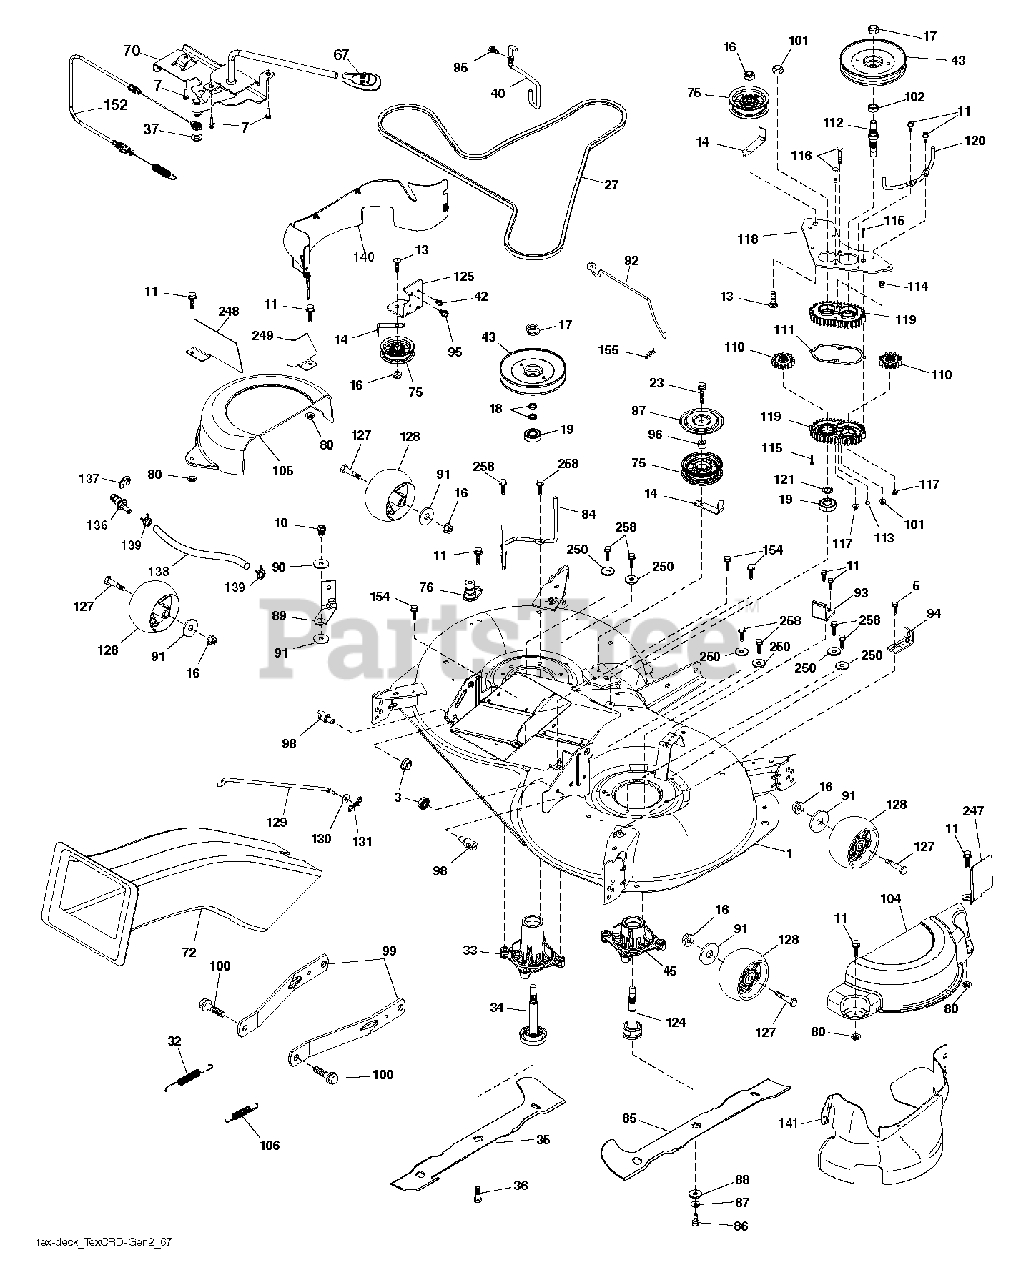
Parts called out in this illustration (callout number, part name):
1	DECK SVCX.107HP.C.BL.498
3	NUT LOCK HEX FLANGE 5/16-18
5	BOLT.5/16HEX.WHS.HD
7	SCREW.#10 X 0.750.BOS
10	SCREW 3/8-16X1
11	SCREW.1/4-20X5/8
13	BOLT.3/8-16X1.50
14	KEEPER, BELT IDLER
16	NUT LOCK FLG 3/8-16 UNC
17	NUT.FLANGE.LOCK.TOP
18	WASHER.SPACER.MANDREL
23	SCREW LT
27	BELT BELT. MOWER DRIVE 97.4 EL
32	SPRING RETURN
33	HOUSING.MANDREL.REV.TALL.N/GRS
34	SHAFT ASM.REV.TALL.N/GREASEBL
35	BLADE.107.LH.SINGLE.NON.QD
36	BOLT.WASHER.ASM.7/16-2
37	WASHER
40	KEEPER BELT ENGINE LH
42	SCREW
43	PULLEY PULLEY MANDREL 5.438 PD
45	RP HOUSING.MANDREL.REV.REVS.
67	HANDLE.CLUTCH.CABLE.LT
70	CLUTCH.ASM.MANUAL.YT.PREDATORQ
72	RB CHUTE 107/97 TEX GENII
75	FLAT IDLER PULLEY
76	1/2" BARB.DECK.WASHOUT.PORT
80	PALNUT 1/4
84	KEEPER KEEPER. LH MANDREL BELT
85	BLADE.107.RH.SINGLE.NON.QD
86	BOLT.3/8-24X1.25GR8. LHTHRD
87	LOCKWASHER
88	WASHER.BLADE
89	ARM BRAKE MOWER
90	SPACER.RETAINER
91	WASHER
92	ROD ASM BRAKE ROD 107 TEX CRD
93	ARM.BRAKE.97.RH
94	BRKT.CLUTCH.CABLE
95	SCREW, 3/8-16X3/4
96	SPACER
97	PROTECTOR
98	STUD.FASTNER.W/ANTI-ROTATE
99	ARM.SUSPENSION.MOWER.R
100	BOLT.SHOULDER
101	NUT.CROWNLOCK.9/16 -18.UNC
102	SPACER BEARING
104	COVER.MANDREL.107.RH.GEN.2
105	COVER.MANDREL.107.LH.GEN.2
106	SPRING.BRAKE.RETURN.38"
110	GEAR GEAR OUTPUT
111	GASKET GASKET GEARCASE
112	SHAFT SHAFT. CRD GEARCASE ADAP
113	PLUG PLUG OIL
114	VALVE VALVE RELIEF
115	SCREW
116	BOLT.CARIGE.SS.1/4-20X1.75GR5
117	NUT T
118	ARM ARM. CLUTCHING 107 TEX CRD
119	GEARCASE GEARCASE SUBASM
120	KEEPER KEEPER. RH MANDREL BELT
121	WASHER WASHER
124	SUB.ASM.REVERSE.THREAD.REV
125	BRACKET BRACKET IDLER CHASSES
127	BOLT.SHOULDER.3/8-16X3-5/8.
128	WHEEL. GUAGE RALLY
129	ROD ROD. SWAY CRD GEN II
130	WASHER
131	PIN.COTTER.5/16.BOW TI
136	PLUG WASHOUT PORT HOOKUP
138	107.WASHOUT.PORT.HOSE (2 2)
139	HOSE.3/8.CLAMP (2 2)
140	GUARD FRENCH 107 TEX ASSEMBLY
141	GUARD SUBASM. 107 TEX GEN 2 RH
152	CABLE CABLE CLUTCH ASSEMBLY
154	SCREW T-30 1/4-20 X
155	RETAINER M
247	GUARD.STEEL.CRD.MANDREL.COV.FR
248	GUARD.STEEL.CRD.MANDREL.COV.FR
249	GUARD.STEEL.CRD.MANDREL.COV.FR
258	BOLT.HEX.WASHR.HED.313-18X1.19
